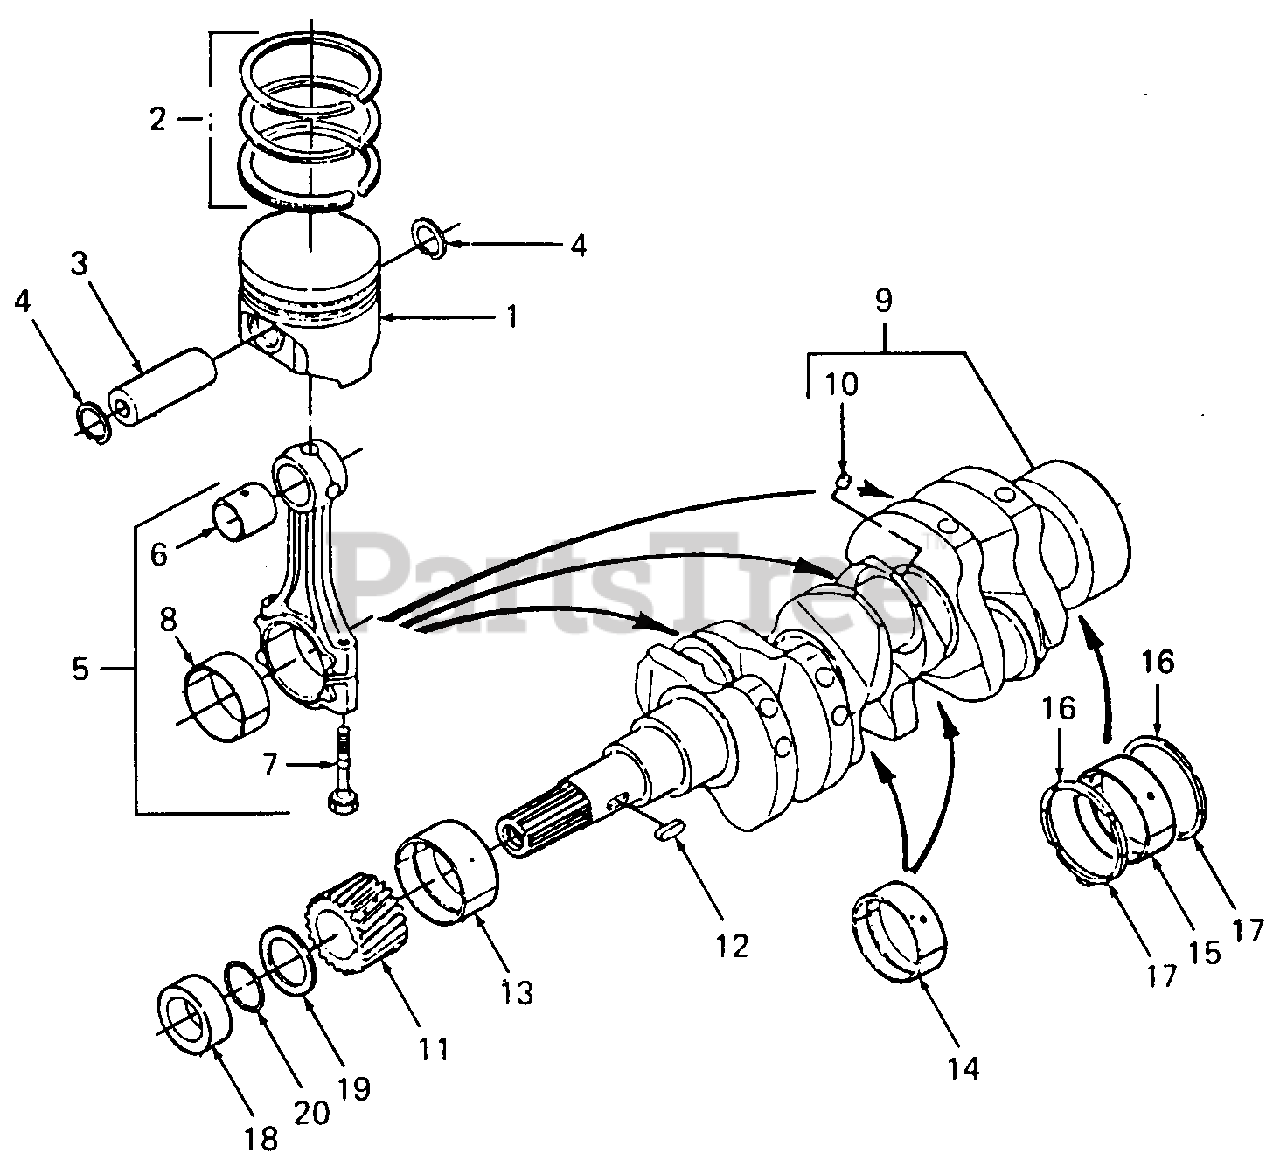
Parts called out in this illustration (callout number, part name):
2	Piston Ring Assy (Std)
4	Cir-Clip, Piston Pin
5	Connecting Rod Assy
6	Bushing, Piston Pin
7	Bolt, Connecting Rod
8	Bushing, Crankpin (Std)
9	Crankshaft Assy
11	Gear, Crankshaft
13	Bearing, Crankshaft Main (Std)
14	Bearing, Crankshaft Main (Std)
15	Bearing, Crankshaft Main (Std)
16	Bearing, Side (Std)
17	Bearing, Side (Std)
18	Collar, Crankshaft
